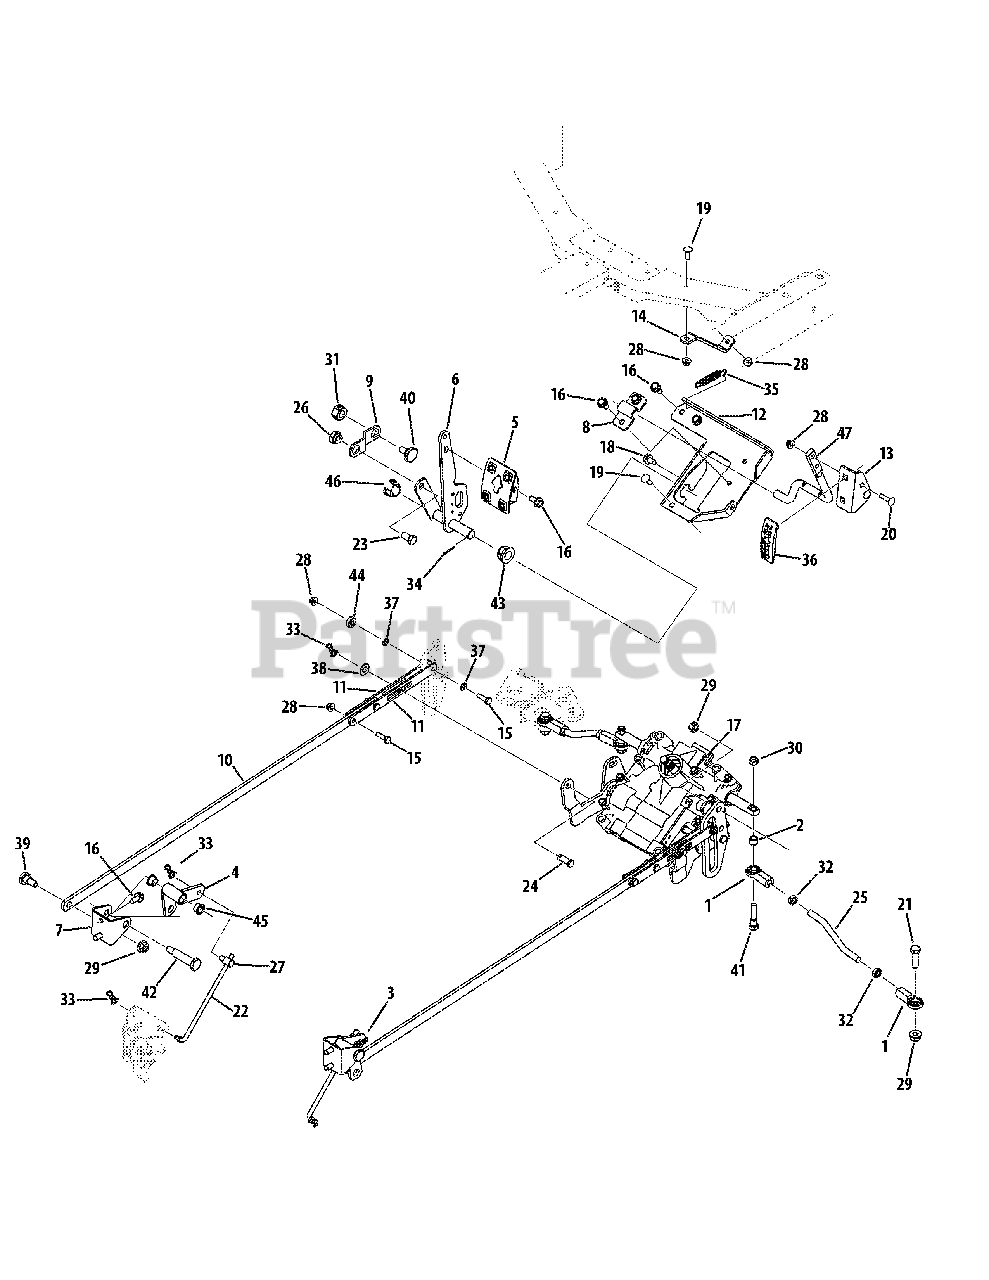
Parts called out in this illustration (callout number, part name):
1	Female Ball Joint, 3.8-24
2	Spacer, 344 x .500 x .375
3	Right Pivot Arm Assembly
4	Left Pivot Arm Assembly
5	Forward Pedal Assembly
6	Forward Bracket Assembly
7	Pivot Mount Bracket
8	Reverse Bearing Bracket
9	Control Bracket
10	Hydro Link Plate
11	Steering Link Plate
12	Pedal Mount Bracket
13	Reverse Pedal Bracket
14	Pedal Mount Plate Support Bracket
15	Hex Screw, 1.4-20 x .875
16	Hex Washer Screw, 5.16-18 x .750
17	Hex Washer Screw, 1.4-20 x .500
18	Hex Washer Screw, 5.16-18 x .625
19	Carriage Screw, 1.4-20 x .75
20	Carriage Screw, 1.4-20 x 1.00
21	Hex Screw, 3.8-16 x 1.25
22	Hex Screw, 1.4-20 x .75
23	Hex Screw, 3.8-16 x .750
24	Clevis Pin, .375 x .969
25	Rod, 3.8 x 5.0
26	Neutral Adjustment Hub
27	Adjustment Ferrule, 1.4-28 x 1.000
28	Flange Lock Nut, 1.4-20
29	Flange Lock Nut, 3.8-16
30	Hex Lock Nut, 5.16-24
31	Hex Lock Nut, 3.8-16
32	Jam Nut, 3.8-24
33	Bow-Tie Cotter Pin, 72
34	Cotter Pin, 3.32 x .750
35	Extension Spring, .429 x 2.515
36	Reverse Foot Pad
37	Flat Washer, .281 x .50 x .04
38	Thrust Washer, .375 x .812 x .060
39	Shoulder Bolt, 3.8-16 x .496 x .336
40	Shoulder Screw, .625 x .217
41	Shoulder Screw, 375 x .48
42	Shoulder Screw, .500 x 1.825
43	Hex Flange Bearing
44	Ball Bearing, .25 x .6875 x .25
45	Flange Bearing, .500 x .34
46	Hex Flange Bearing, .628
47	Reverse Pedal Rod
48	Hydro Control Rod
